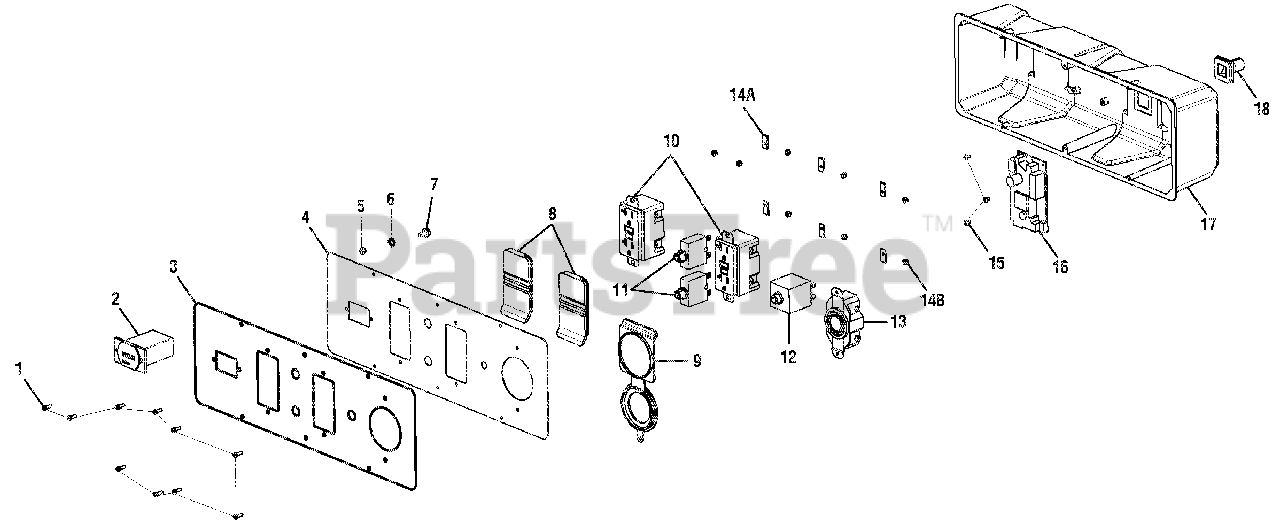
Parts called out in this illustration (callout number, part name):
1	Screw (6-20 x 3/8 in.)
2	Hour Meter (120 Volt)
3	Label (Power Outlet)
4	Front Panel
5	Lock Nut (M4)
6	Star Washer (ID6.4 x OD11 x 0.6t)
7	Bolt (M5 x 10 mm, Hex Hd.)
8	Outlet Cover (120 Volt)
9	Outlet Cover (240 Volt)
10	120 Volt Duplex Receptacle (GFCI)
11	Circuit Breaker (20 Amp, 125 Volt)
12	Circuit Breaker (30 Amp)
13	Twist Lock Receptacle (120/240 Volt, 30 Amp, L14-30R)
14B	Lock Nut
15	Screw (M3 x 5 mm)
16	Circuit Board
17	Control Box (Back Panel)
18	Rubber Boot
